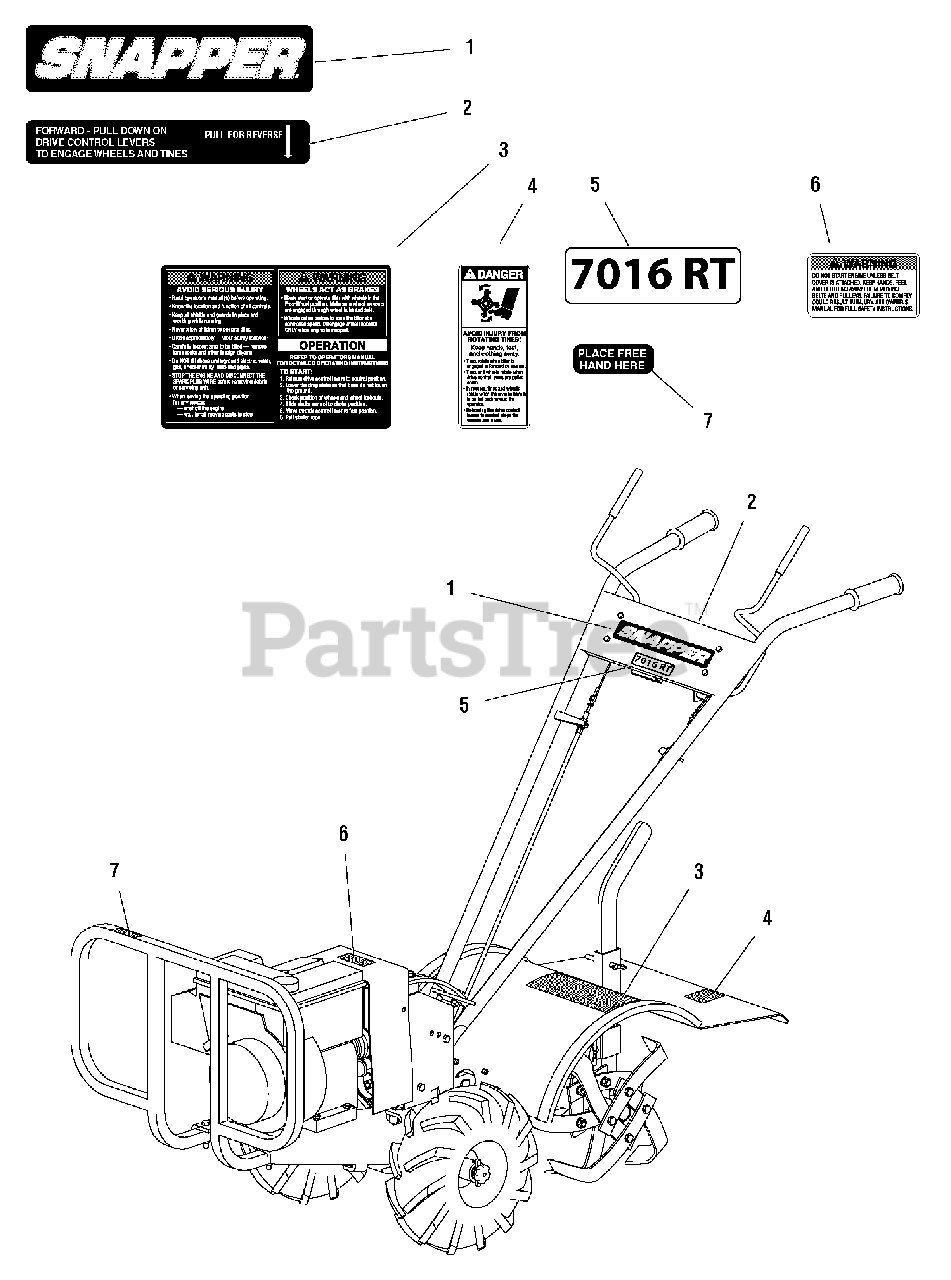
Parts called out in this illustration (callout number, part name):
1	DECAL, Snapper
2	DECAL, Console Forward/Reverse Instructions
3	DECAL, Hood, Operator Instructions Label
4	DECAL, Danger, Tine Hood Label
5	DECAL, 7016 RT
6	DECAL, Warning, Belt Cover
7	DECAL, Brush Bar (on 7 HP model only)
